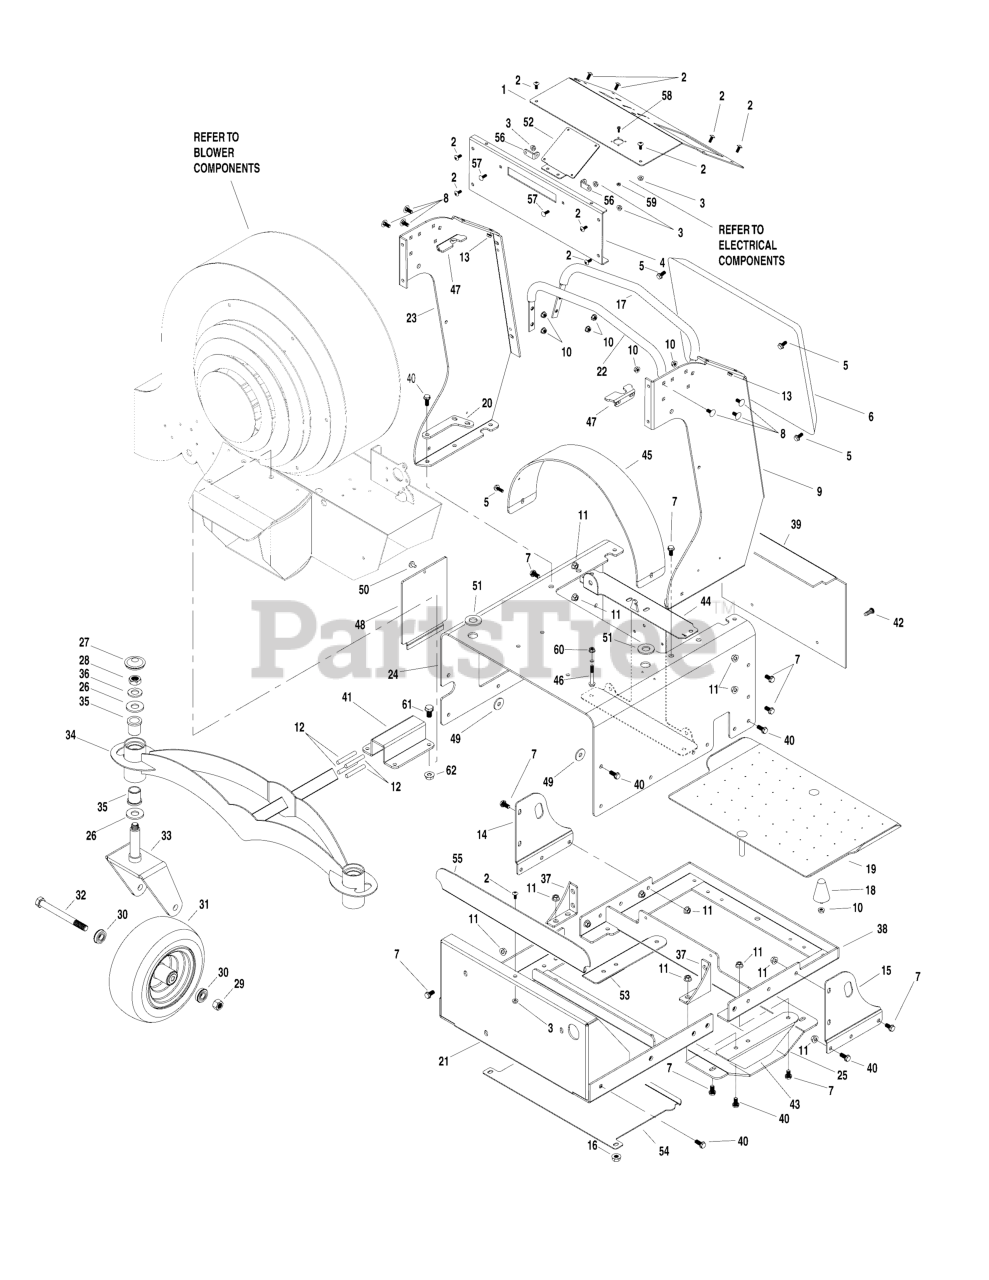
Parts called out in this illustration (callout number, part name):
1	PLATE, DASH PANEL, X3,Z3 (ZF17452)
2	BOLT, 1/4-20 X 3/4, FLANGE, CZ
3	NUT, 1/4-20, SERRATED FLANGE, YZ
4	WELD, DASH FRONT PANEL (ZFT17451)
5	BOLT, 5/16-18 X 3/4, FLANGE, CZ
6	KNEE PAD, BLWR
7	BOLT, 3/8-16 X 3/4, FLANGE, CZ
8	BOLT, 5/16-18 X 3/4, CARRIAGE, GD5, CZ
9	CONTROL TOWER X3, LH - RED
10	NUT, 5/16-18 HEX SERRATED FLANGE (SMALL)
11	NUT, 3/8-16 Hex Large Serrated Flange
12	CORD, RUBBER
13	NUT, 1/4-20, RIV, CZ
14	PLATE, TIE DOWN RH (X310-T2006)
15	PLATE TIE DOWN LH - RED
16	NUT, 3/8-16 Hex Large Serrated Flange
17	REAR HANDLE, BLWR - RED
18	BUMPER, RUBBER, 5/16-18
19	WELD, FOOT PLATE (X310-2011)
20	PLATE, UPPER BEAM MOUNT - BLK
21	WELD, X3 FRONT CHASSIS - BLK
22	FRONT HANDLE, BLWR - RED
23	CONTROL TOWER X3, RH - RED
24	WELD, MOTOR BOX - RED
25	PLATE, SKID - BLK
26	WASHER, 1 X 10GA, MACH, CZ
27	CAP, GREASE, PLASTIC
28	NUT, 3/4-10, NYLOCK JAM, CZ
29	NUT, 5/8-11 HEX NYLOCK FLANGE
30	BEARING, CASTER
31	TIRE ASSEMBLY, 11 X 4.00 - 5
32	BOLT, 5/8-11 X 6-1/2, CZ
33	WELD, CASTER YOKE, X3 (109-10-T2010)
35	BUSHING, FLANGE
36	BUSHING, 1 X 10GA, MACHINED, YZ
37	WELD, TRANS 90° MOUNT BRACKET (X3-14-3017)
38	WELD, X3 REAR CHASSIS - BLK
39	PLATE, TOE KICK, FB2000 - RED
40	BOLT, 3/8-16 X 1, SER FLG GD5, CZ (15062)
41	PLATE, BENT, FRONT END TORSION
42	SCREW, 5/16-18 X 1/2, SLF TPNG, CZ
43	BRACKET, BOTTOM CHASSIS RIGHT - BLK
44	WELD TRANS I-BEAM (XF1730)
45	PLATE, BELT GUARD X3 - RED
46	BOLT, 5/16-18 X 2-1/4 SER FLNG GD5, CZ
47	BRACKET, NEUTRAL CENTERING, CZ
48	PLATE, BATTERY DOOR - RED
49	SPACER, MOTOR BOX 10GA
50	KNOB, 1/4-20 X 1/2 CAP SCREW
51	GROMMET, RUBBER
52	BRACKET, RELAY MOUNT - BLK
53	BRACKET, BOTTOM CHASSIS LEFT - BLK
54	GUARD, LOWER DEBRIS (ZF1445)
55	GUARD, FORWARD DEBRIS - BLK
56	BRACKET, L HEADLIGHT MOUNT - BLK
57	BOLT, 1/4-20 X 3/4, CARRIAGE, CZ (17109)
58	SCREW, #8-32 X 3/8, ALLEN, SS
59	NUT, #8-32, KEPS, CZ
60	NUT, 5/16-18 HEX SERRATED FLANGE (SMALL)
61	BOLT, 1/2-13 X 1-1/4, FLANGE, CZ
62	NUT, 1/2-13 SERRATED FLANGE, CZ
